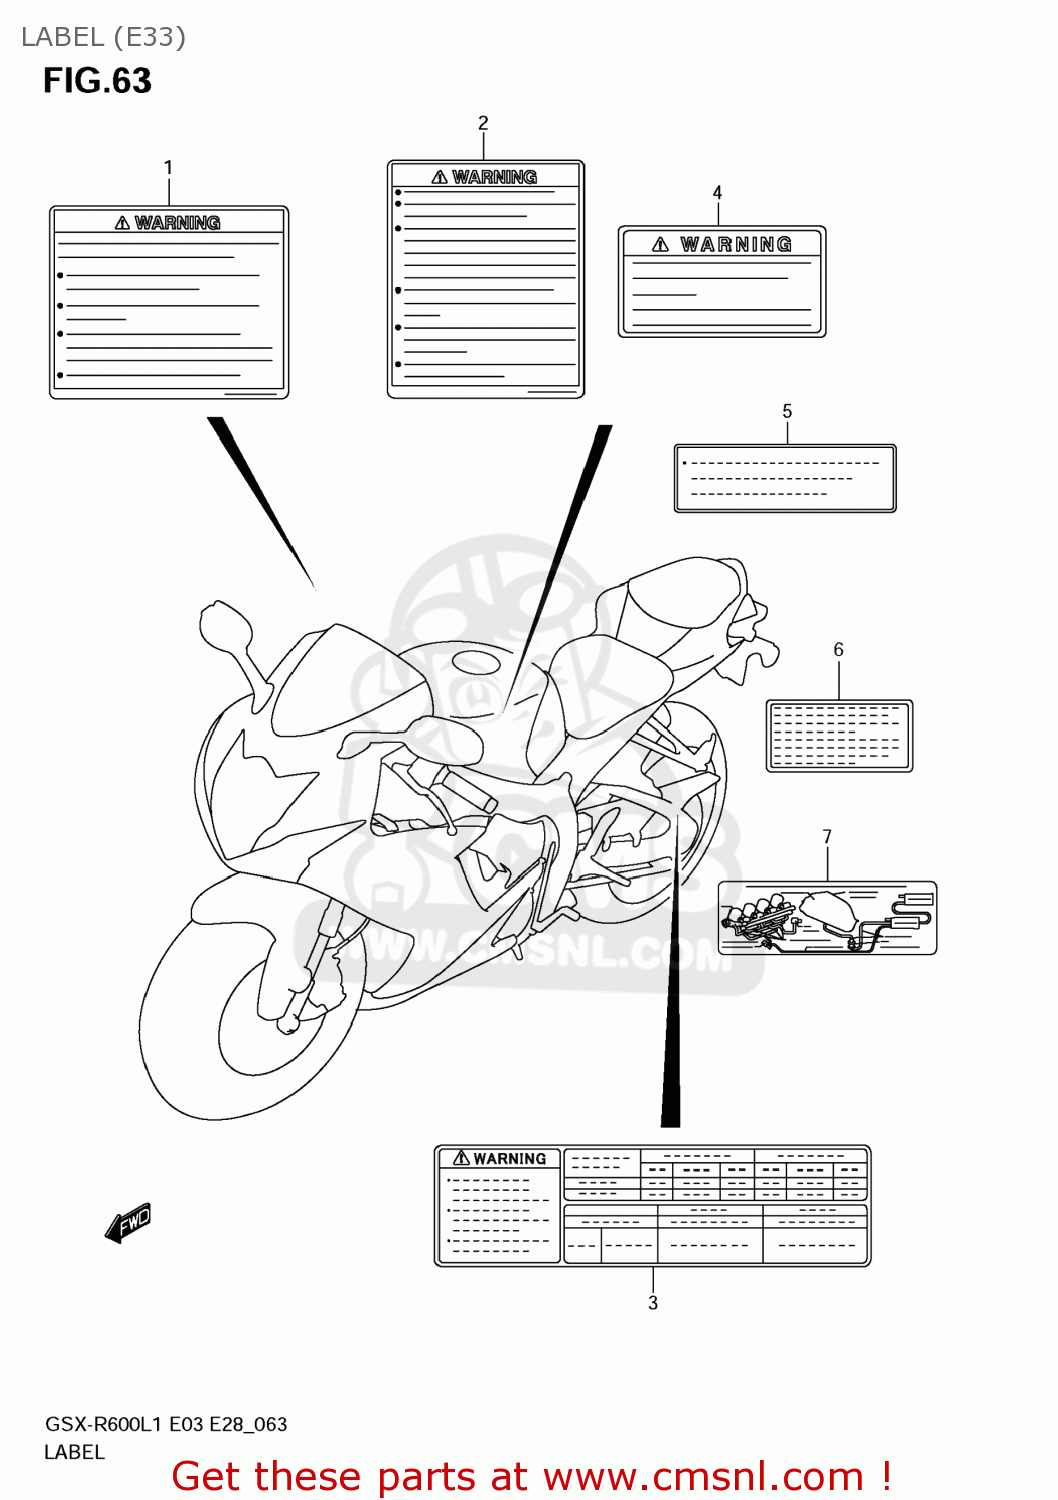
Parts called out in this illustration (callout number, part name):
1	LABEL,GENERAL WARNING
2	LABEL,SCREEN
3	LABEL,TIRE INFORMATION
4	LABEL,WARNING STEERING
5	LABEL,FUEL INFORMATION
6	LABEL,MANUAL NOTICE
7	LABEL,VACUUM HOSE ROUTING
8	MANUAL,OWNER'S
